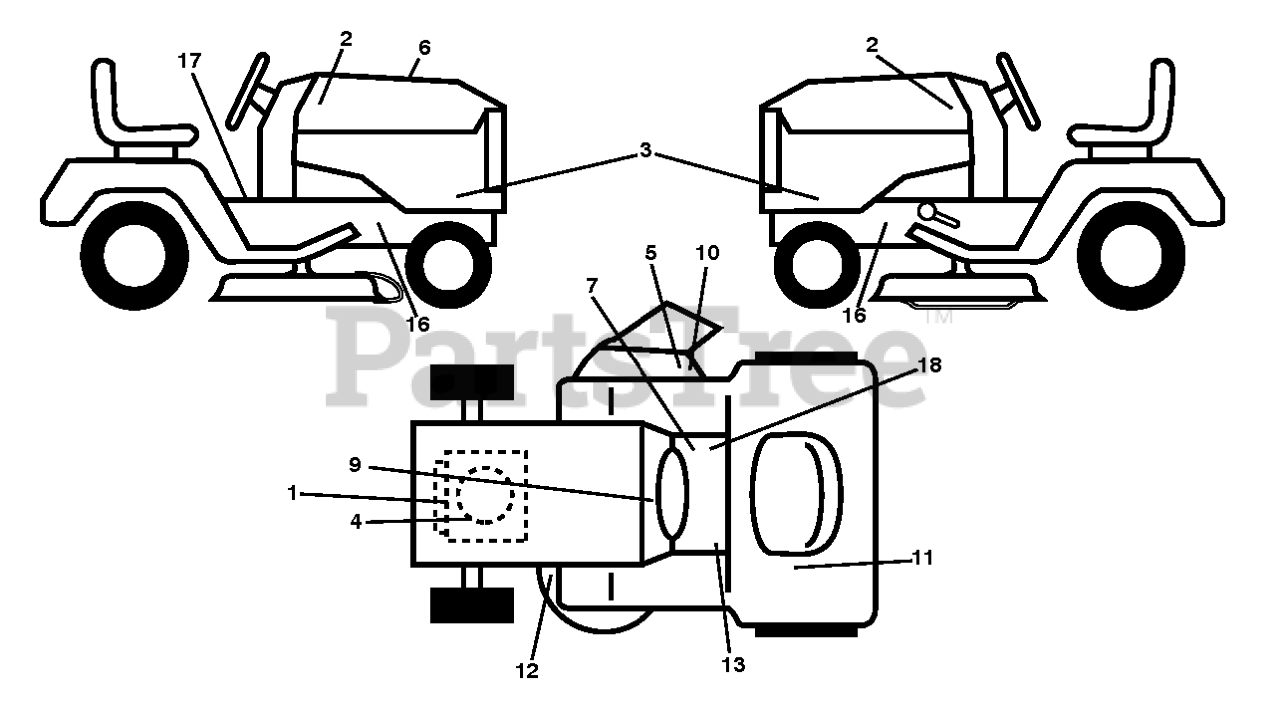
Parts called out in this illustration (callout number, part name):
1	DECAL, ENG. HP
2	DECAL.BADGE.170MM.TEXTLOGO.
3	DECAL DECAL.SDPNL.GT2.YTH2246
4	DECAL.ENGINE.WARNING
5	DECAL, DECK DEFLECTOR, WARNING
7	DECAL.FNDR.SDLE.BRAKE.CLUTCH.6
9	DECAL BTRY SYMBOLS
10	DECAL.DFLCTR.WARNNG.CTFNGR.SYM
11	DECAL.WARN.FUEL.RESERVE
12	DECAL.V-BELT.SCH.42/46"MEC/ELE
13	DECAL.READ.OWN.MAN.SYMBOL.LT
16	DECAL.CHASSIS.HOT.MUFFLER
17	DECAL.PARKING.BRAKE.SADDLE.LT
18	DECAL.PEDALS.SYMBOL
